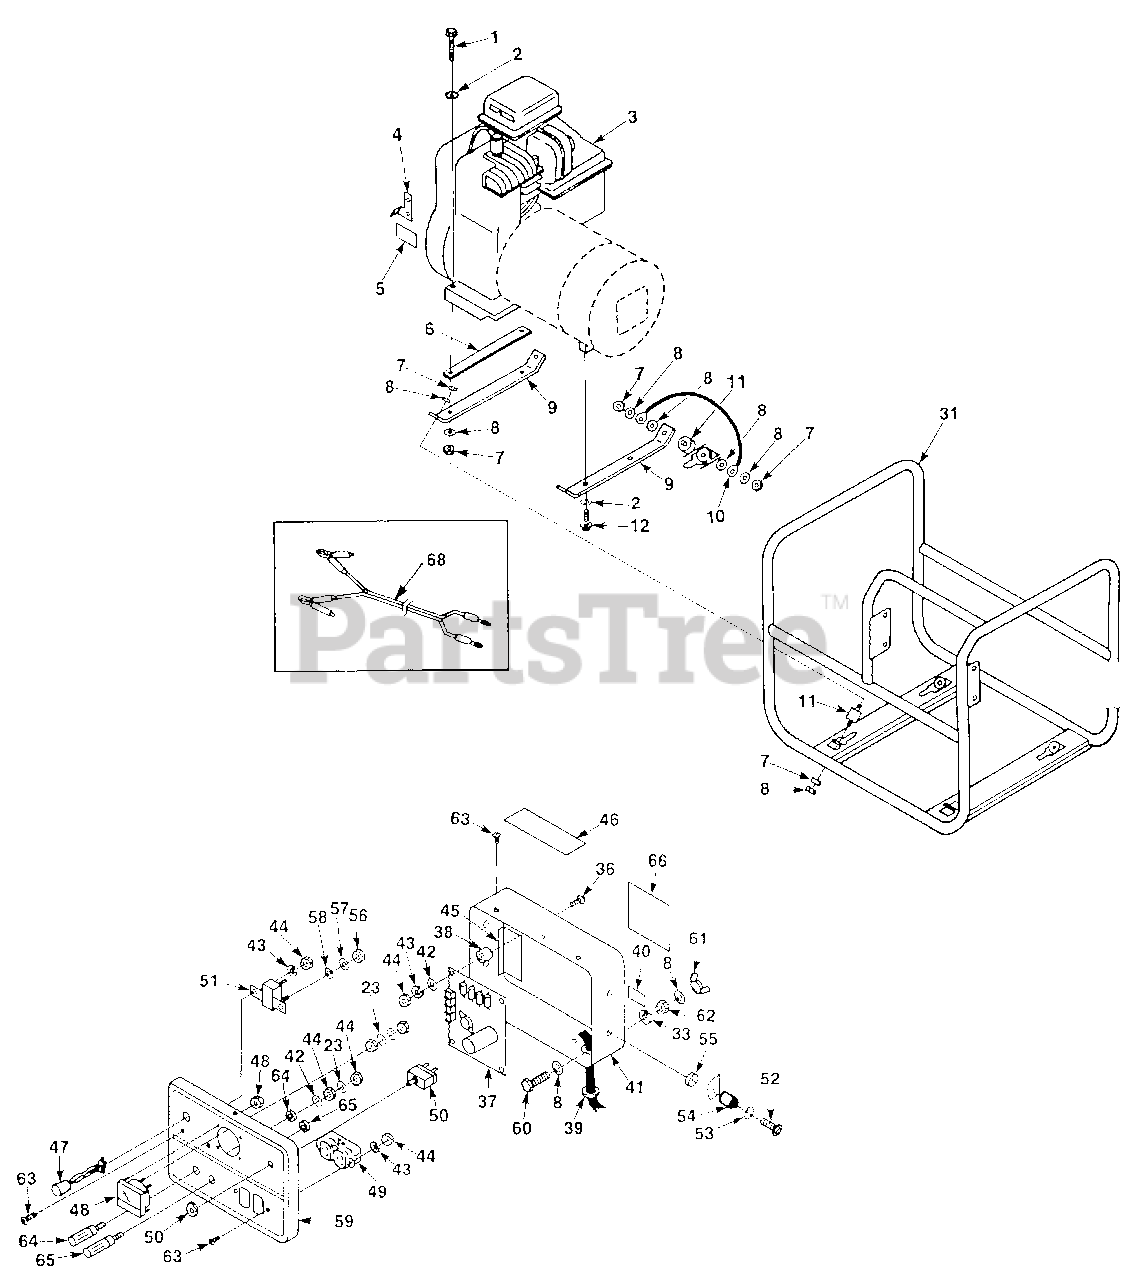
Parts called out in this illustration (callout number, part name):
1	SCREW- Hex Hd. 5/16-18 x 1 1/2"
2	WASHER- Lock Int. 5/16
3	ENGINE- 5 H.P. Briggs
7	NUT- Hex 5/16-18
8	WASHER-Int.
9	SUPPORT- Eng. & Gen.
10	STRAP-Ground
11	ISOLATOR-Vibration
12	SCREW-Hex taptite 5/16-18 x 1"
23	WASHER-Lock Int. #8
31	ROLL CAGE
33	WASHER- Lock 5/16"
36	SCREW- #8- 32 x 5/8"
37	VOLTAGE REGULATOR
38	SPACER- 1/4"
39	GROMMET
40	DECAL-Ground
41	CONTROL BOX
42	WASHER-Flat #8
43	WASHER-Lock #8
44	NUT- Hex 8-32
45	DECAL-Schematic
46	DECAL- Warning
47	PILOT LITE
48	VOLTMETER
49	RECEPTACLE- Duplex
50	BREAKER- Circuit (AC)
51	BREAKER- Circuit (DC)
52	SCREW- Pan hd. 1/4-20 x 3/4"
53	WASHER- Flat 1/4"
54	SLEEVE- Grommet
55	GROMMET- Isolator
56	NUT- Hex 10-32
57	WASHER- Flat #10
58	WASHER- Lock #10
59	CONTROL PANEL
60	SCREW- Cap hex hd. 5/16-18 x 1"
61	NUT- Wing 5/16-18
62	NUT- Hex 5/16-18
63	SCREW- Pan hd., 8-32 x 3/8"
64	POST- Binding (Black)
65	POST- Binding (Red)
66	DECAL- Caution
68	LEAD- D.C.
